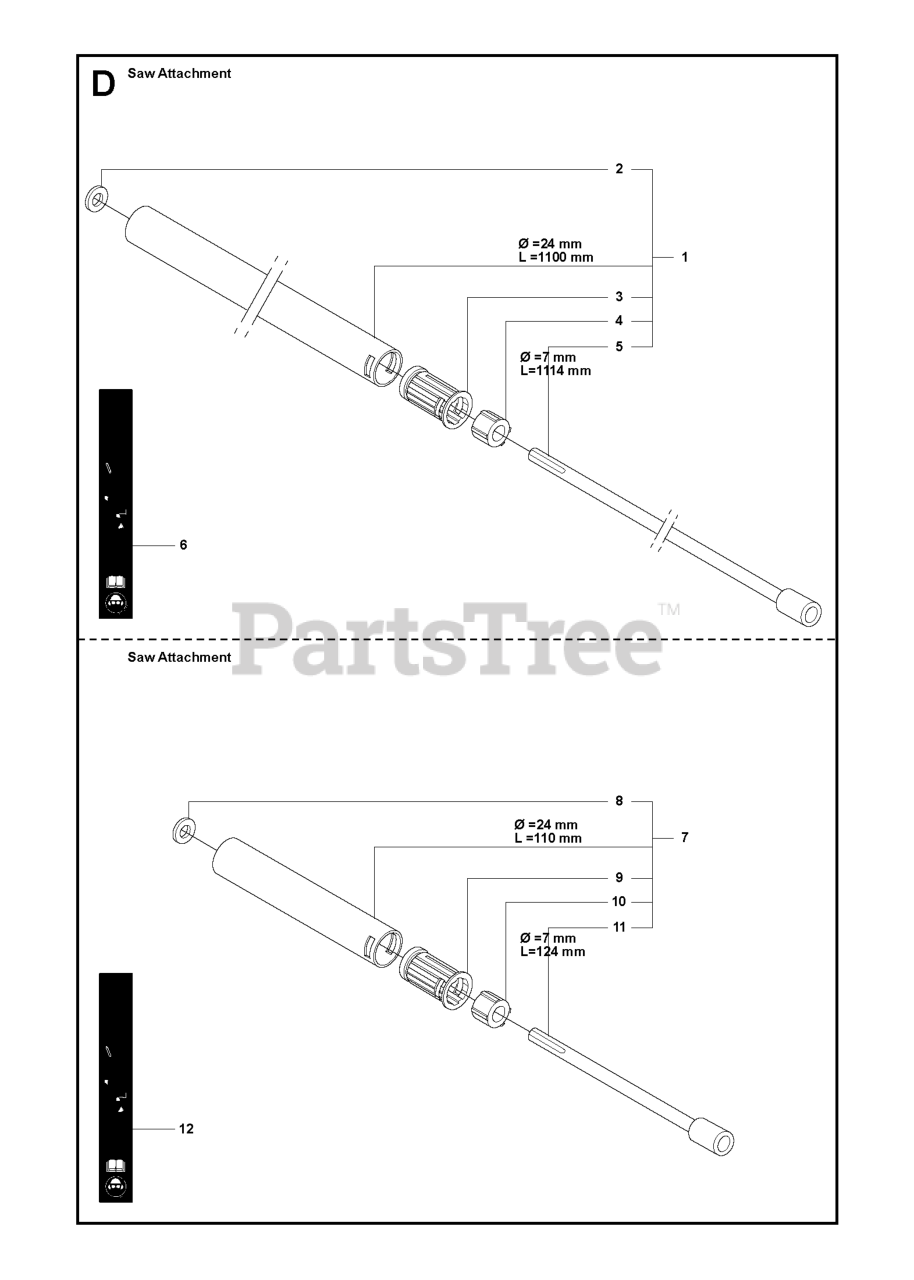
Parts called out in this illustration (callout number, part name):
1	TUBE
4	BUSHING
5	SHAFT
7	TUBE
10	BUSHING
11	SHAFT
